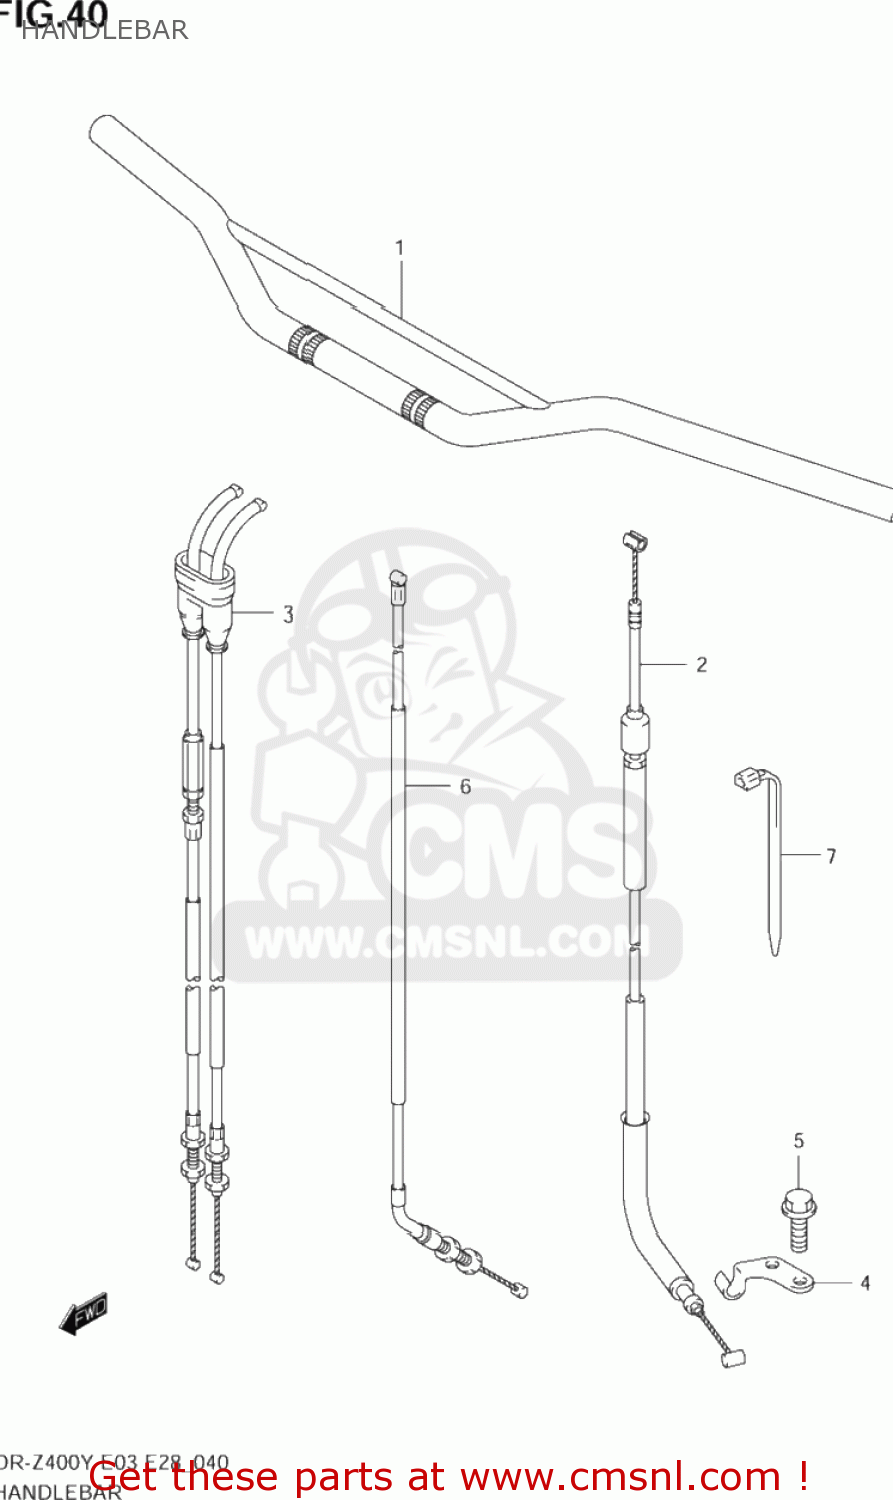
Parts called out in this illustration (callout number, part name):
1	HANDLEBAR(SILVER)
2	CABLE ASSY,CLUTCH
3	CABLE SET,THROTTLE
4	STOPPER,CLUTCH CABLE
5	BOLT(6X15)
6	CABLE ASSY,DECOMP
7	CLAMP(L:235)
